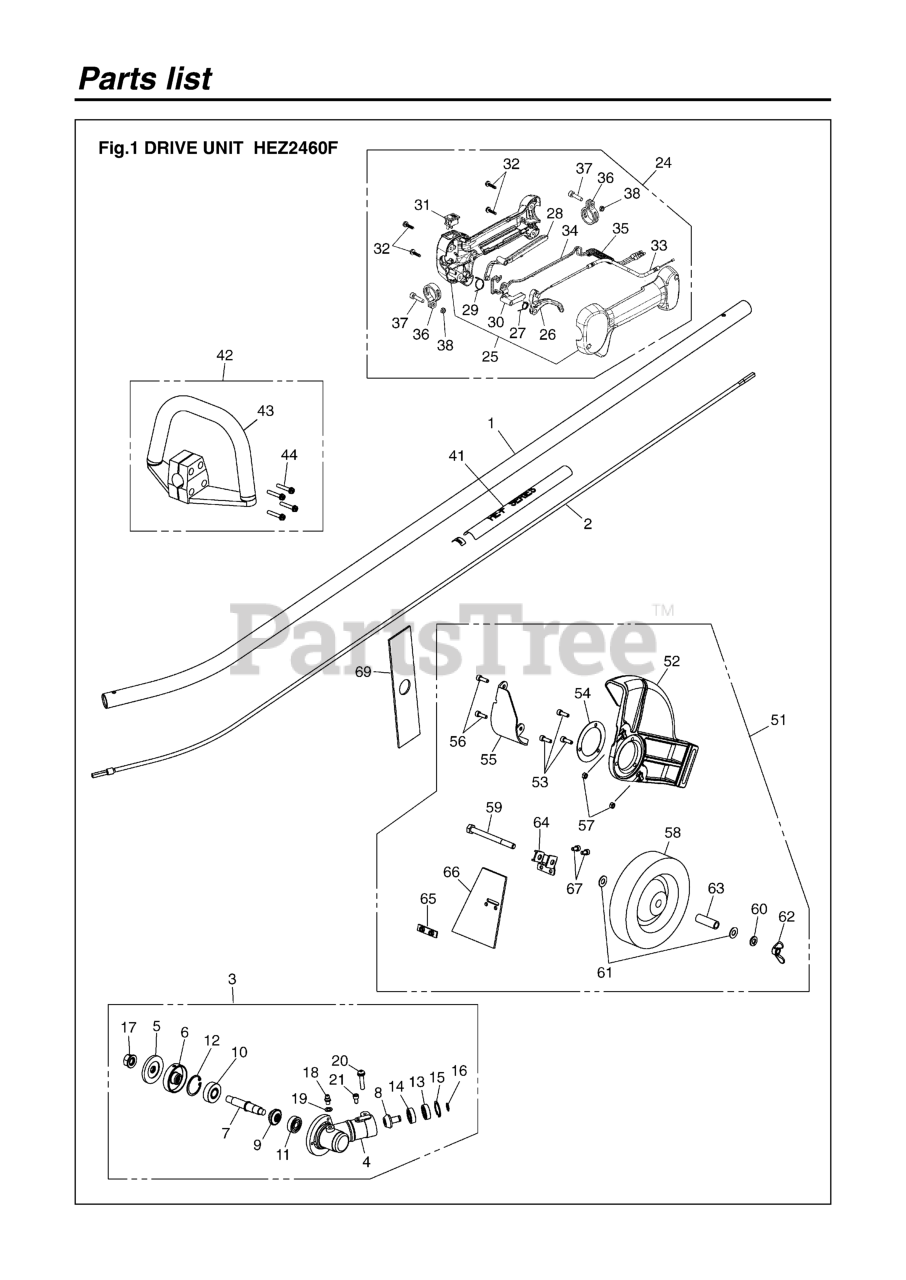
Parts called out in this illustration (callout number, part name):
1	PIPE COMP
2	SHAFT COMP
3	GEARCASE
4	GEARCASE
5	HOLDER B
6	HOLDER A
7	SHAFT
9	GEAR
10	BEARINGxxx
11	BEARING
14	BEARING (RPLS T3
16	SNAP RING
18	FITTING, GREASE
19	WASHER, M6 x .8
21	BOLT, M5 x 10
24	GRIP ASSY
25	GRIP, HALF SET
26	LEVER, THROTTLE
27	SPRING, THROTTLE
28	LEVER FOR GRIP (
30	LEVER JOINT
34	CORD - C
37	BOLT (RPLS 28501
38	NUT
41	NAMEPLATE
42	HANDLE ASSY. (RP
43	HANDLE T
51	GUARD ASSY
52	Guard
53	BOLT (M5x0.8-16)
55	PROTECTOR
56	BOLT (M5x0.8-16)
57	NUT, M5 x 4
58	WHEEL (RPLS T305
60	WASHER, SPRING(T
61	WASHER
66	RUBBER (FLAP)
67	BOLT, M5 x 10
69	BLADE, EDGER (RP
